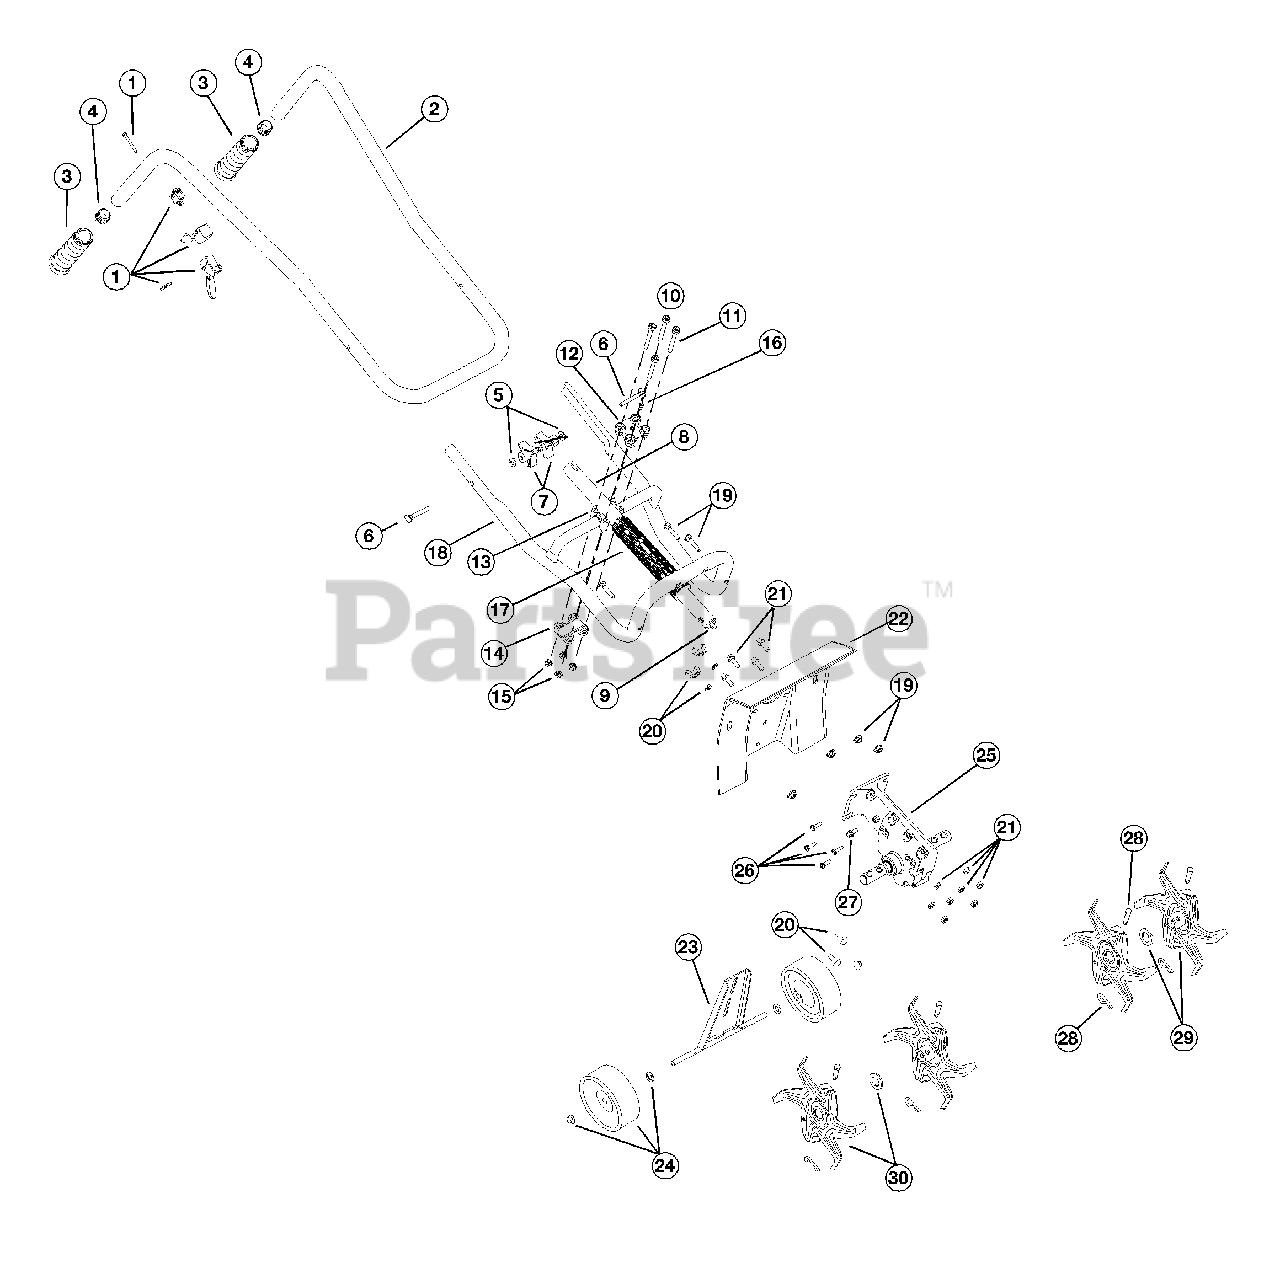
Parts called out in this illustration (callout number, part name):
1	Throttle Trigger and Cable Assembly
2	Handle Bar Assembly, Upper
4	Tube Closure
5	Washer
7	Knob, 3 prong
8	Drive Shaft Housing Assembly
9	Flexible Drive Shaft
10	Handle Bracket Assembly
12	Upper Handle Clamp
13	Middle Handle Clamp
14	Lower Handle Clamp
16	Anti-Rotation Screw
18	Lower Handle Bar
19	Hardware, Handle Bar Mounting (lower)
20	Wheel Bracket Mounting Hardware
21	Guard Mounting Hardware
23	Wheel Bracket Assembly
24	Wheel Assembly
25	Gear Box Assembly
27	Sleeve Retainer Bolt
28	Tine Fastener Assembly
29	Tine Assembly (Left Outer or Right Inner)
30	Tine Assembly (Left Inner or Right Outer)
